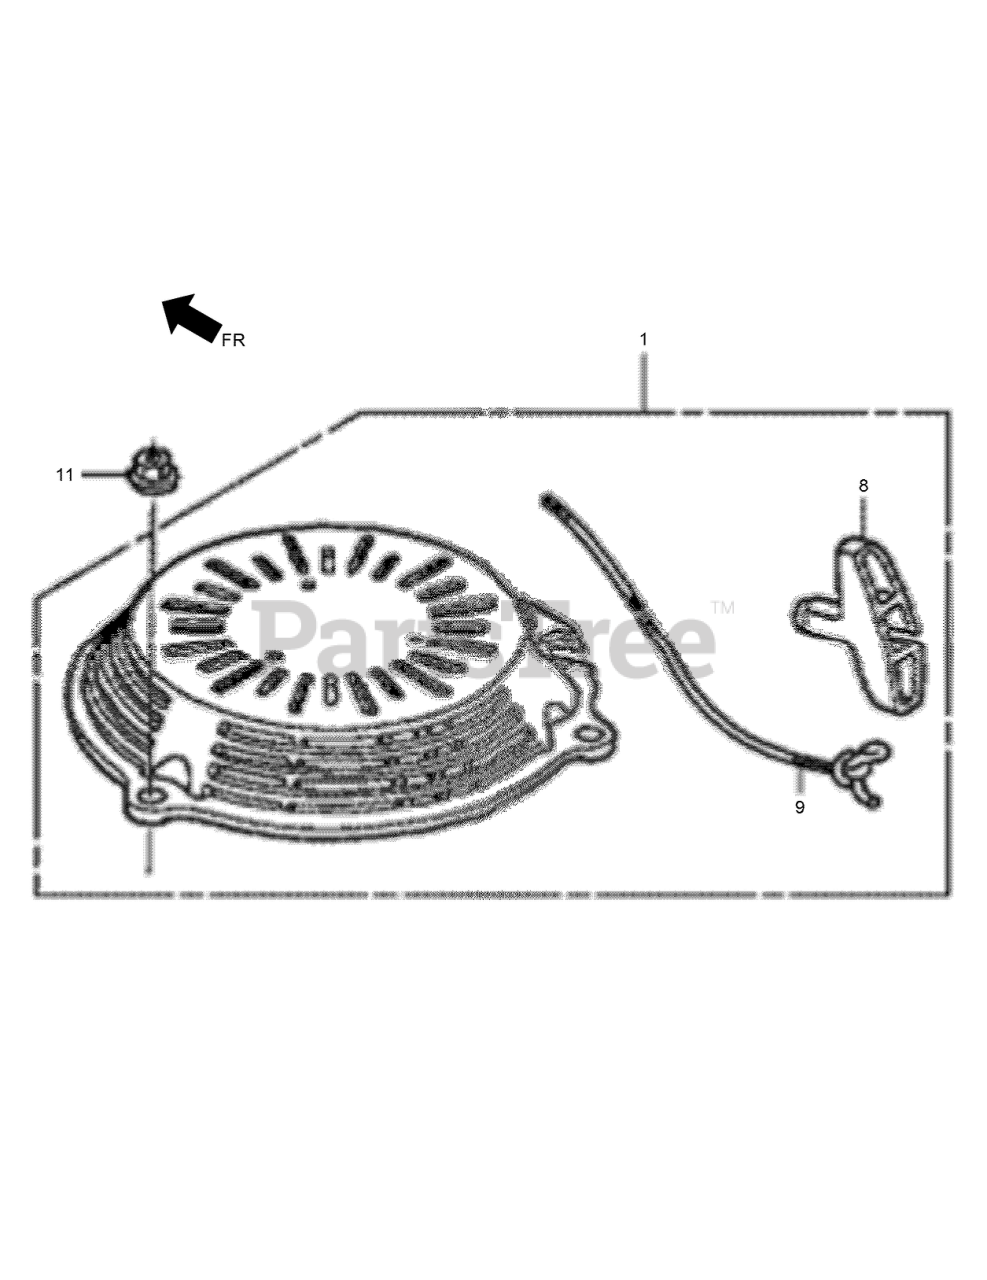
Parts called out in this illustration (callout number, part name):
1	STARTER ASM-RECOIL (NH1)
8	GRIP-STARTER
9	ROPE-RECOIL STARTER
11	NUT-FLANGE-6MM
